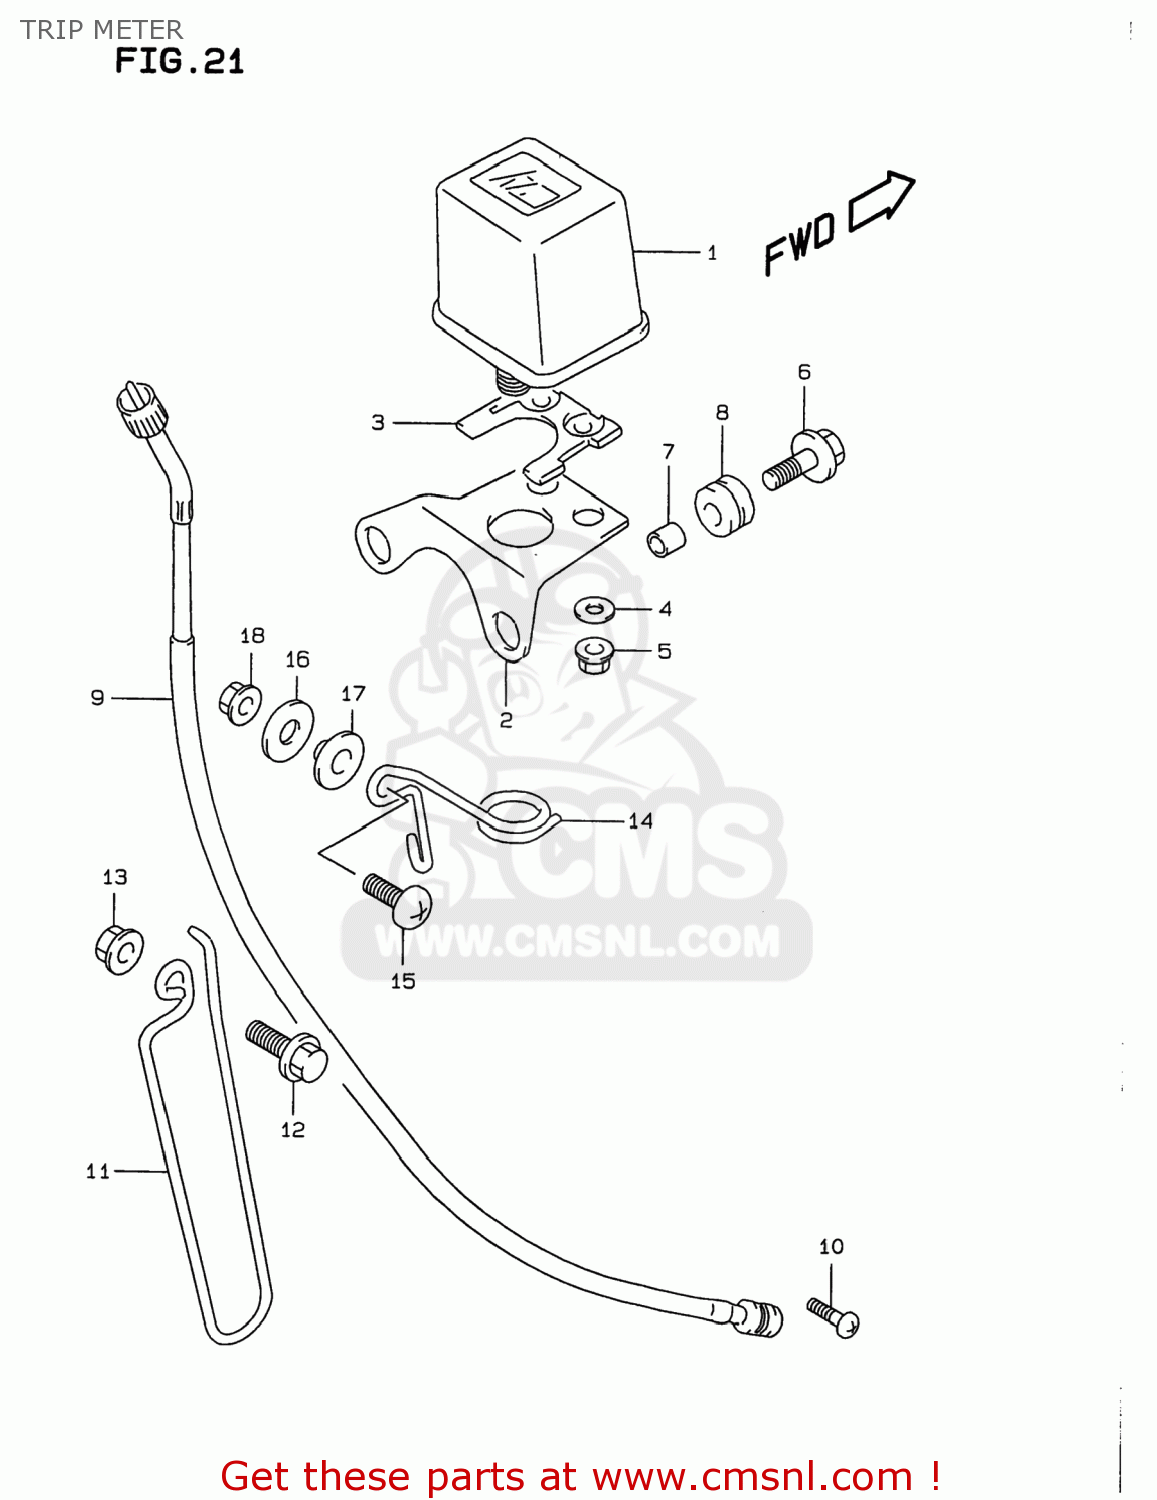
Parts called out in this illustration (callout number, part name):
1	TRIP METER
2	BRACKET
3	CUSHION
4	WASHER (4.3X13X0.80)
5	NUT
6	BOLT(6X25)
7	SPACER(6.1X8X9.5)
8	CUSHION
9	CABLE ASSY,SPEEDOMETER
10	SCREW
11	GUIDE,METER CABLE NO.2
12	BOLT(6X16)
13	NUT
14	GUIDE,SPEEDOMETER CABLE
15	SCREW
16	WASHER(6.5X18X1.6)
17	WASHER
18	NUT 6MM
